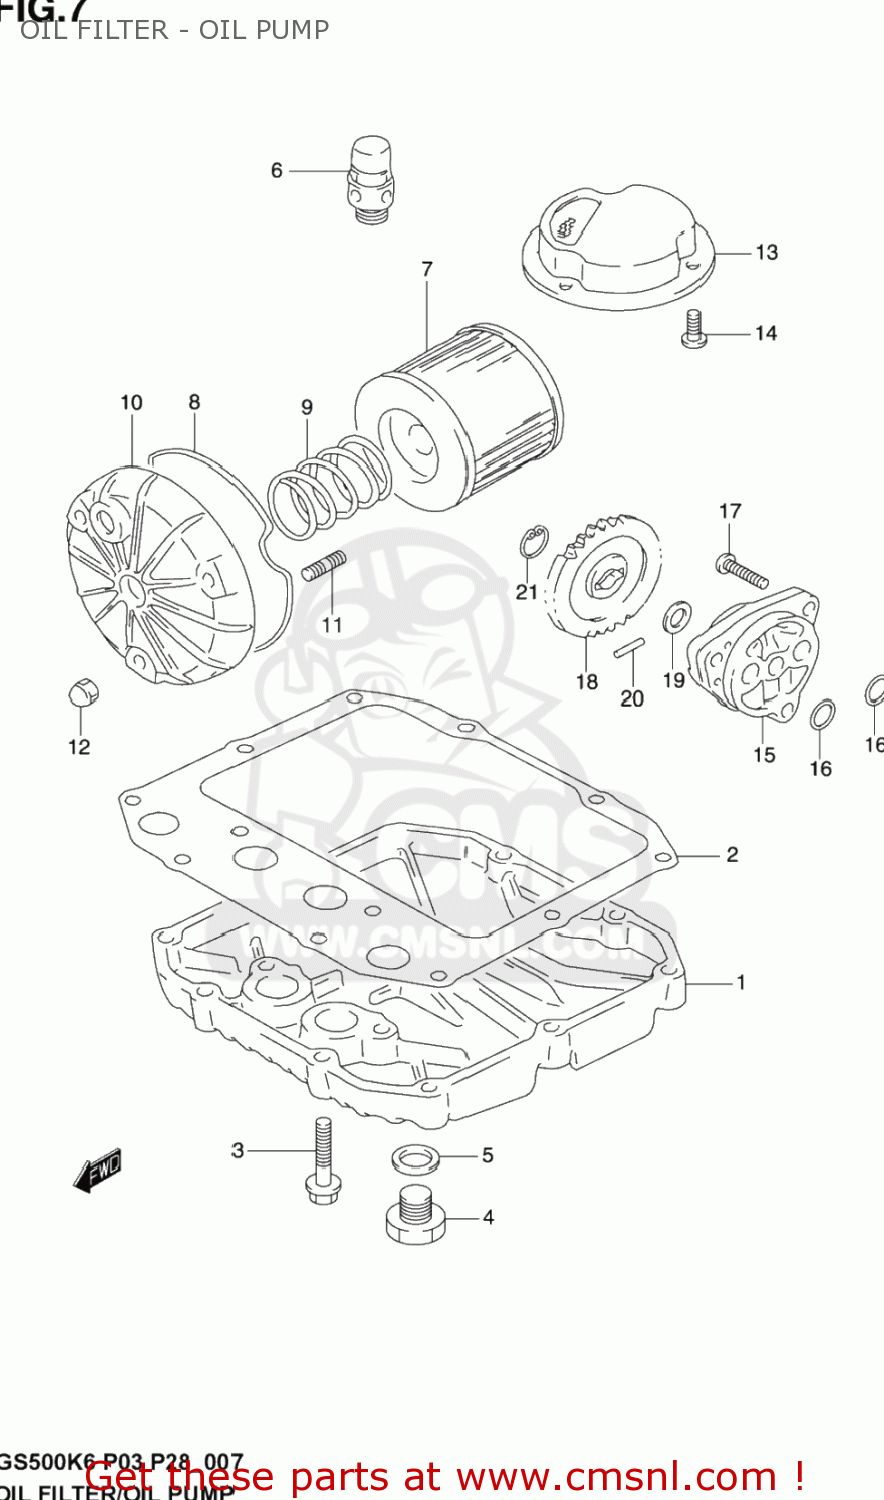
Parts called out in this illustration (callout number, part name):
1	PAN,OIL
2	GASKET,OIL PAN(ASB) (NAS)
3	BOLT
4	PLUG(14X12)
5	GASKET(13.8X18.8X4.8) (NAS)
6	REGULATOR,ENGINE OIL(6.5K)
7	FILTER ASSY,ENGINE OIL
8	O RING,OIL FILTER CHAMBER CAP
9	SPRING
10	CAP,OIL FILTER
11	STUD 6X20
12	NUT
13	STRAINER,ENGINE OIL
14	BOLT
15	PUMP ASSY,ENGINE OIL
16	O RING(D:1.9,ID:13)
17	SCREW
18	GEAR,OIL PUMP DRIVEN
19	SHIM(10X18X0.5)
20	PIN(4X15.8)
21	CIRCLIP,10MM
